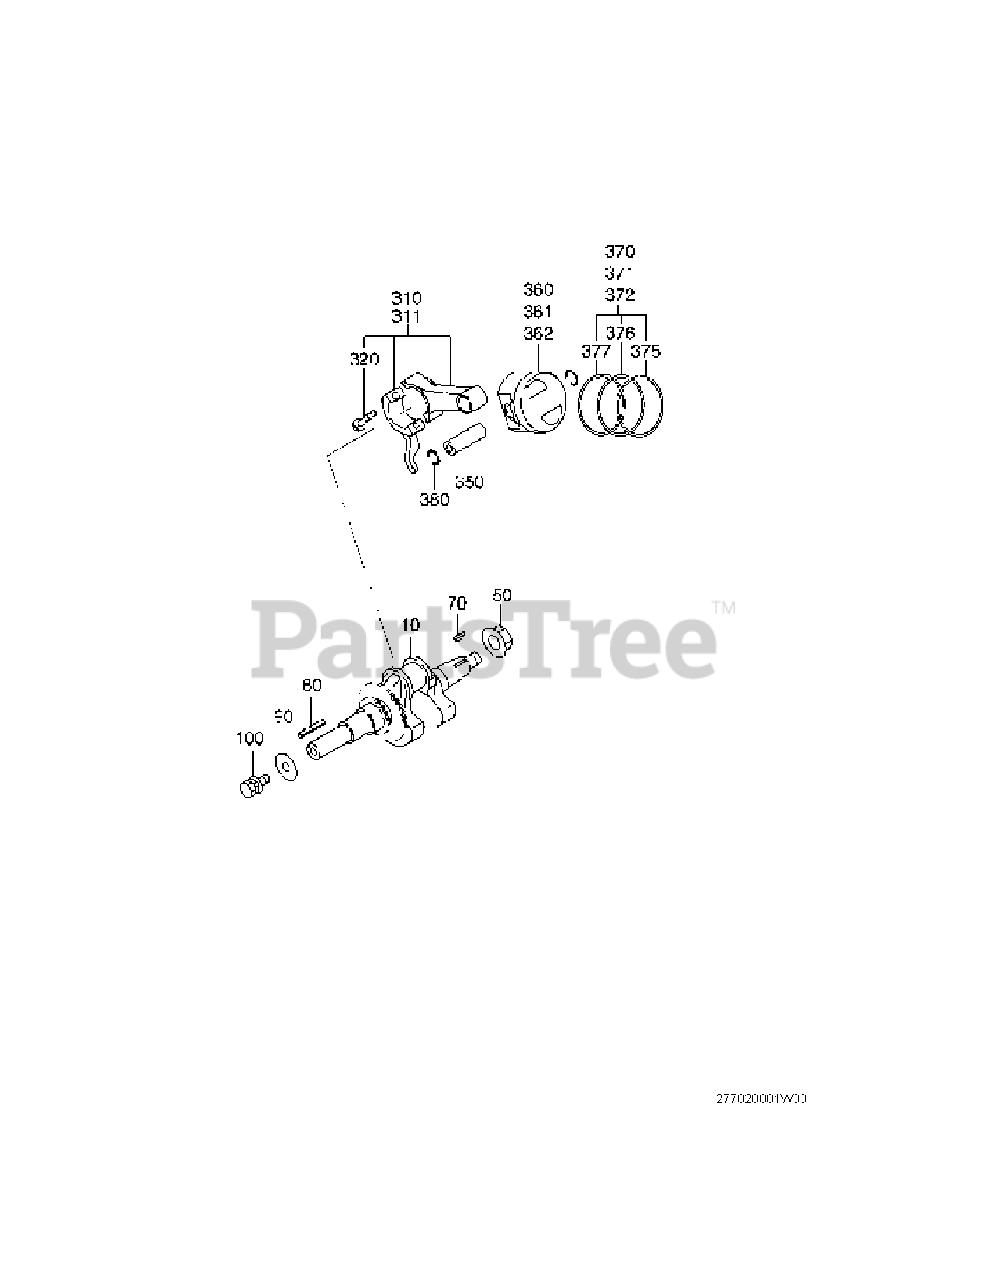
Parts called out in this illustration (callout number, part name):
10	CRANK SHAFT CP
310	CONNECTING ROD AY
311	CONNECTING ROD AY
320	CONNECTING ROD BOLT
370	PISTON RING SET
371	PISTON RING SET
372	PISTON RING SET
